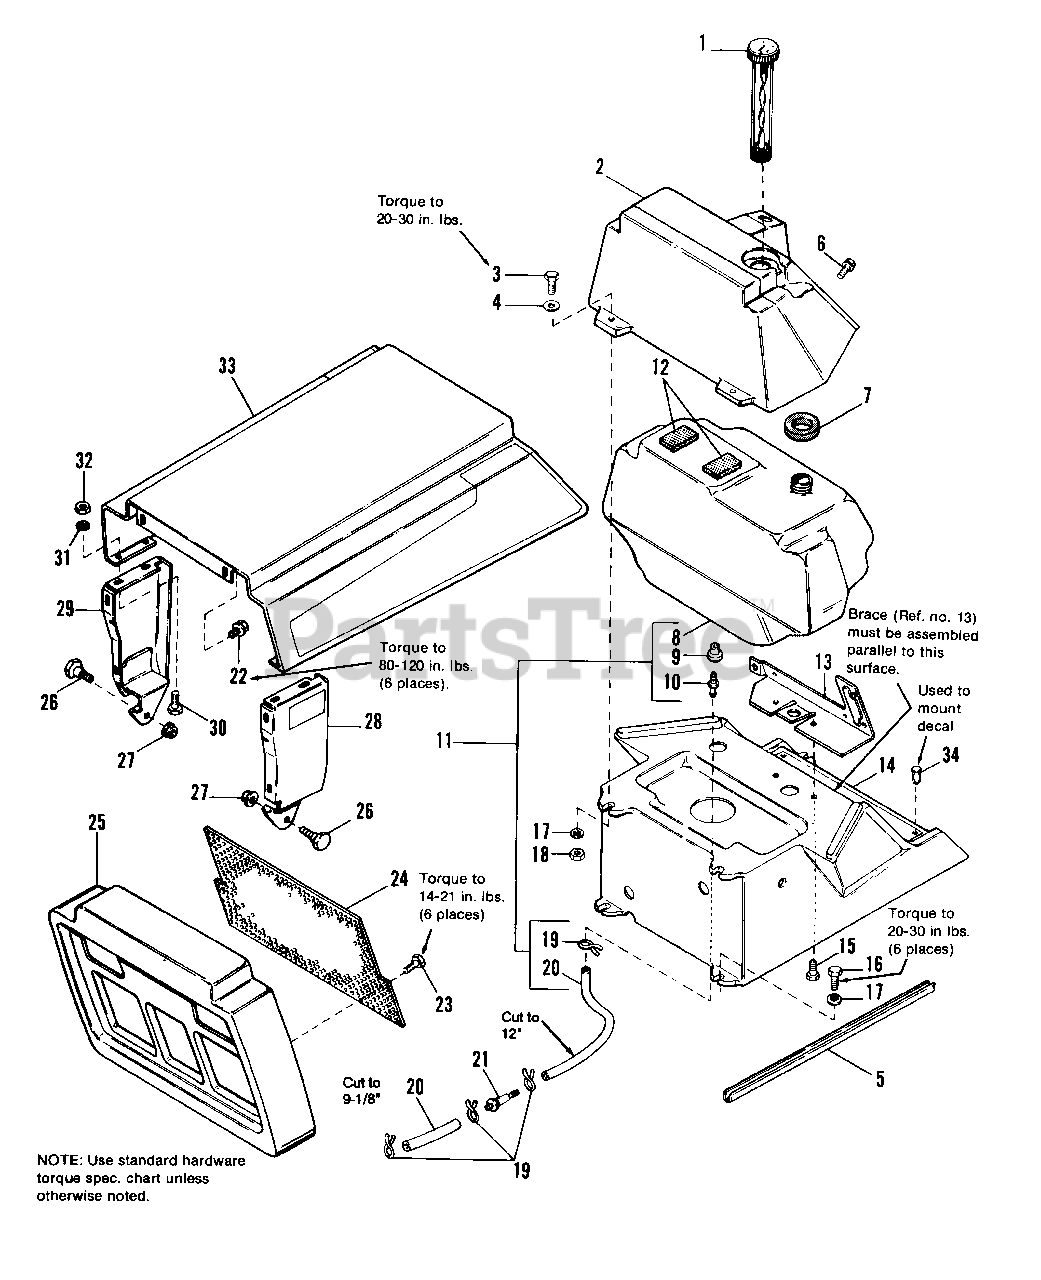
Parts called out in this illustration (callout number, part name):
1	CAP, w/Gas Gauge
2	DASHBOARD, Top
3	CAPSCREW, Hex, 1/4-20 x 1-1/4
4	WASHER, 1/4
5	EDGING, Lower Dash
6	SCREW, Hex Washer Hd., 1/4-14 x 5/8
7	WASHER, Foam
11	TANK ASSY., Fuel (Ref. No. 11 incl. Ref. Nos. 8, 9, 10, 19 Qty. 1 & 20)
14	DASHBOARD, Bottom
15	SCREW, Taptite, 1/4-20 x 3/4
16	SCREW, Taptite, 1/4-20 x 1
17	LOCKWASHER, Dish, 1/4
18	LOCKNUT, Hex, 1/4-20
19	CLAMP, Hose
20	HOSE, Fuel, 45" long (Cut toHOSE, Fuel, Cut to 12th needed-See notes on page 28)
21	FILTER, Fuel
22	SCREW, Plastite, 1/4 x 1
23	SCREW, Plastite, #10-14 x 1/2
25	GRILLE (Incl. Ref. No. 22)
26	BOLT, Shoulder, 5/16-18 x 7/8
27	LOCKNUT, Flange, Whiz, 5/16-18
28	PANEL ASSY., L.H.
29	PANEL ASSY., R.H.
30	CAPSCREW, Hex, 1/4-20 x 1/2
31	LOCKWASHER, 1/4
32	NUT, Hex, 1/4-20
34	CLIP, Canoe
